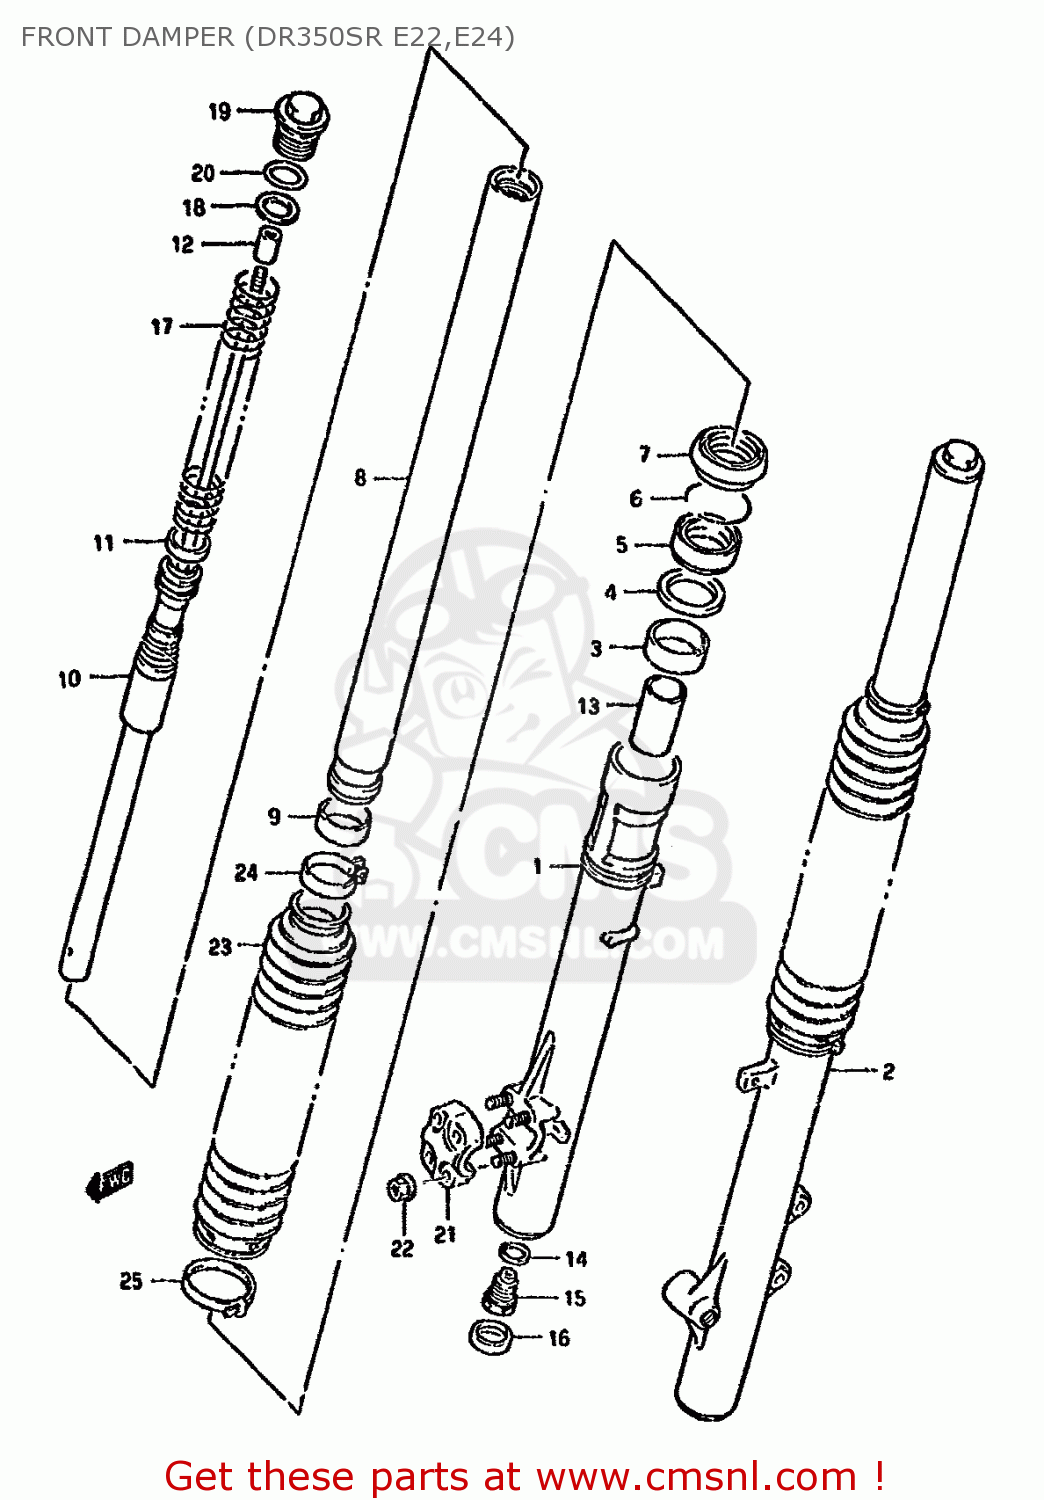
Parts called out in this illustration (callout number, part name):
1	TUBE,OUTER,RIGHT
2	TUBE,OUTER,L
3	BUSH,GUIDE
4	SPACER,SEAL
5	SEAL,OIL
6	CIRCLIP,FORK OIL SEAL
7	DUST SEAL
8	TUBE,INNER
9	BUSH,SLIDE
10	CYLINDER
11	BUSH,SLIDE
12	NUT,ROD
13	PIECE,OIL LOCK
14	GASKET (NAS)
15	CTR BOLT
16	CAP
17	SPRING,MAIN
18	SEAT,SPRING LWR
19	BOLT,FORK
20	O RING
21	HOLDER,AXLE
22	NUT,HOLDER
23	BOOT
24	BOLT,CTR
25	JACK ASSY
26	BOOT
27	BAND,BOOT UPR
28	BOLT(5X27)
